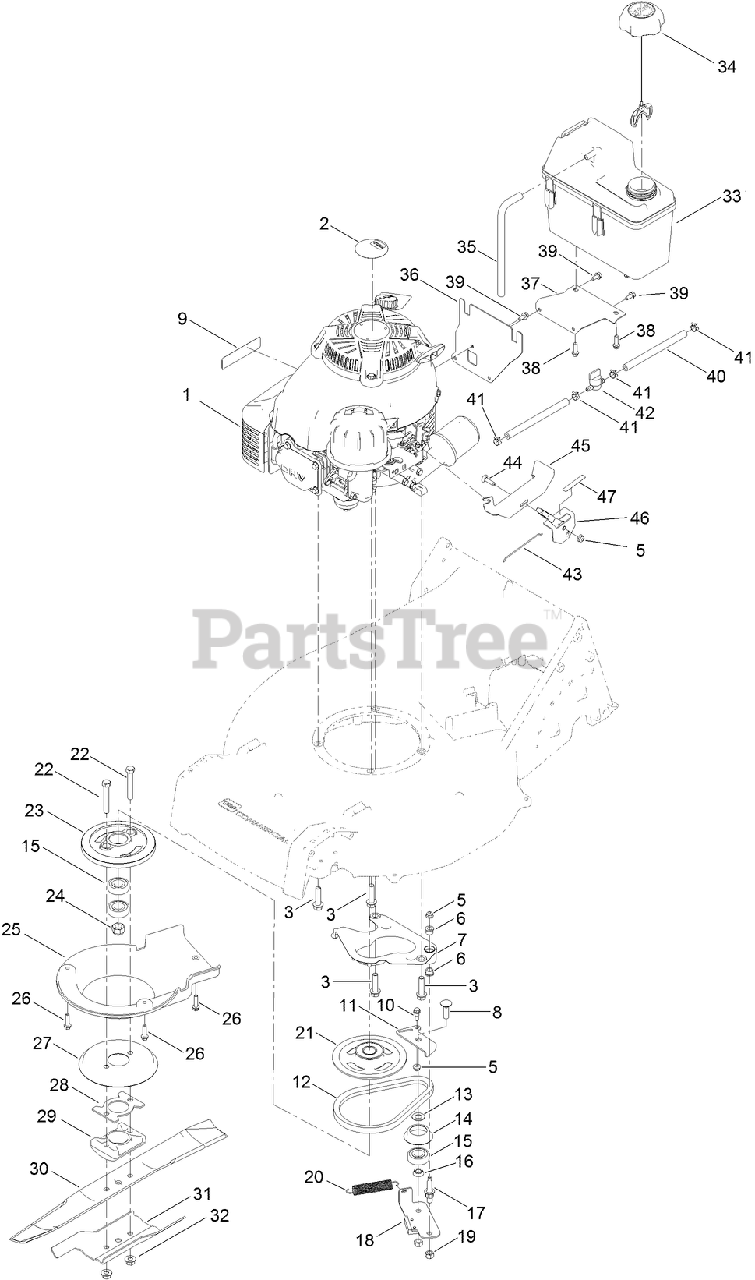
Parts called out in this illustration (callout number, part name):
3	SCREW-HWH
5	NUT-HF
6	BUSHING-FLANGE
7	PLATE-ANCHOR
8	BOLT-CARR
9	DECAL-ARRESTOR, SPARK
10	BOLT-SHOULDER
11	PLATE-GUIDE, BBC
13	SPACER
14	RETAINER-BELT
15	BEARING-BALL
16	SPACER-BEARING
17	BOLT-SHOULDER
18	PLATE-BRAKE
19	NUT-HEX
20	SPRING-TENSION, BRAKE
21	PULLEY
22	SCREW-HH
24	NUT-HEX
26	SCREW-HWHTF
27	DISC
28	SPACER-DRIVER, BLADE
29	SUPPORT-BLADE
30	BLADE-21IN, RECYCLING
31	ACCELERATOR-BLADE
32	NUT-FLANGE, LOCK
33	TANK-FUEL
34	CAP-FUEL
35	HOSE-VENT, CANISTER
36	BRACKET-TANK, MOUNTING
37	BRACKET-TANK, SUPPORT
38	SCREW-HWH
39	SCREW-HWH
40	HOSE-FUEL
41	CLAMP-HOSE
42	VALVE-FUEL
43	WIRE-CONTROL
44	SCREW-CARR
45	BRACKET-MOUNT, THROTTLE
46	CONTROL-THROTTLE
47	DECAL-THROTTLE, CHOKE
